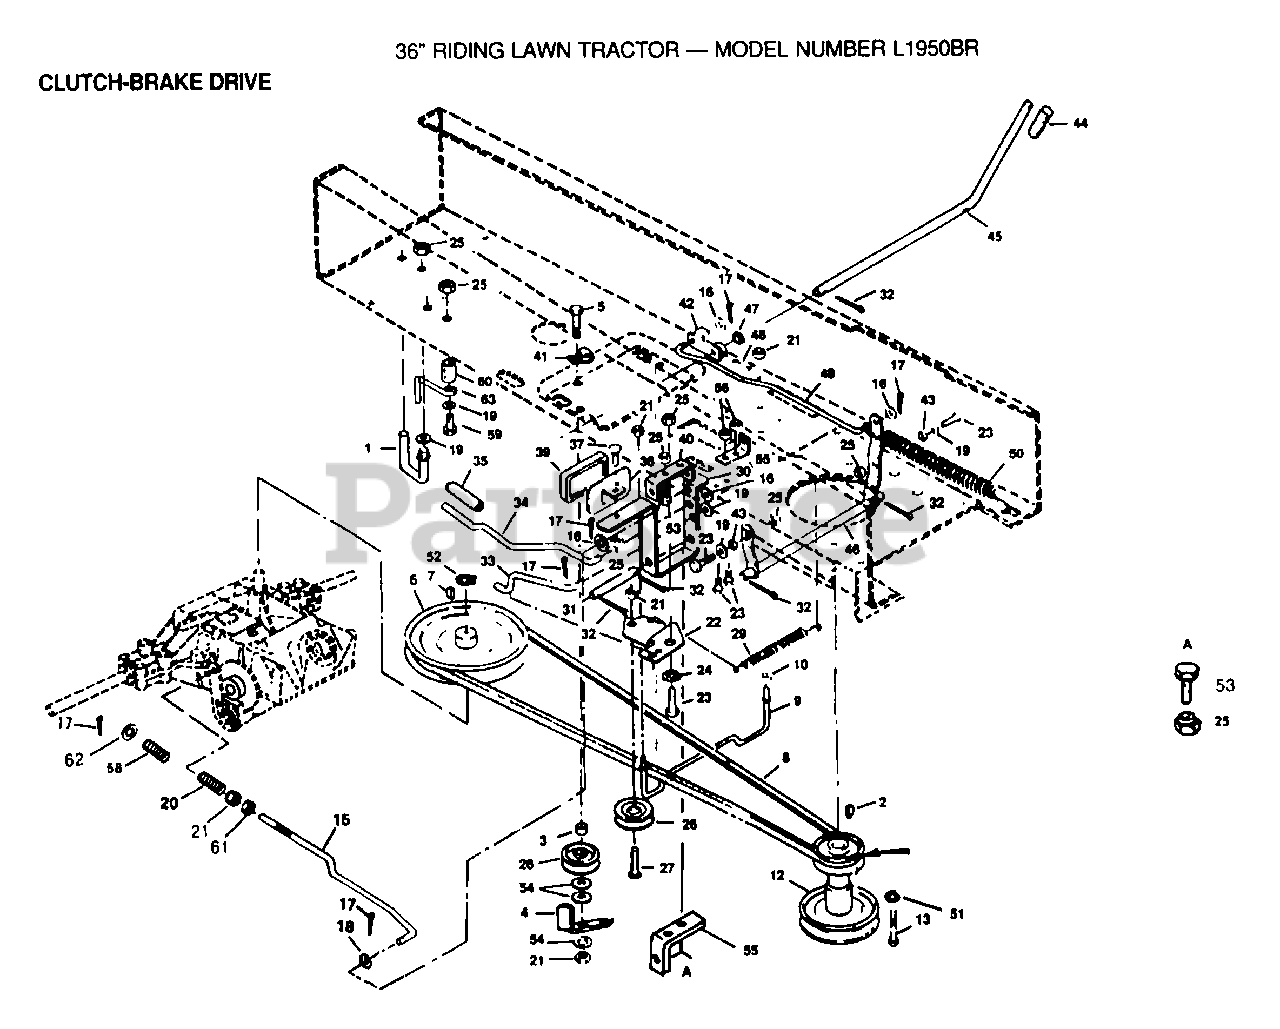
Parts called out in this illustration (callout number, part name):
1	BELT GUIDE T
4	BELT KEEPER T
6	PULLEY-TRANS T
9	MID BELT GUIDE LT
10	WASHER
13	BOLT RER
15	BRAKE ROD
16	WASHER
18	WASHER
19	WASHER M
20	BRAKE SPRING T
22	IDLER BRACKET
23	BOLT
29	IDLER SPRING
30	FOOT PEDAL LT
32	PIN COTTER 1/8
34	PARK BRK ROD T
36	PEDAL PLATE LT
37	BOLT
39	FOOT PAD LT
40	PEDAL BRACKET T
45	CLUTCH HANDLE L
49	BALDE ROD LT
51	LOCKWASHER
53	BOLT
54	WASHER
55	ARM BRAKE
58	SPRING T
59	BOLT.HEX.5/16-1.5
61	NUT
62	WASHER
63	BELT RETAINER GT
